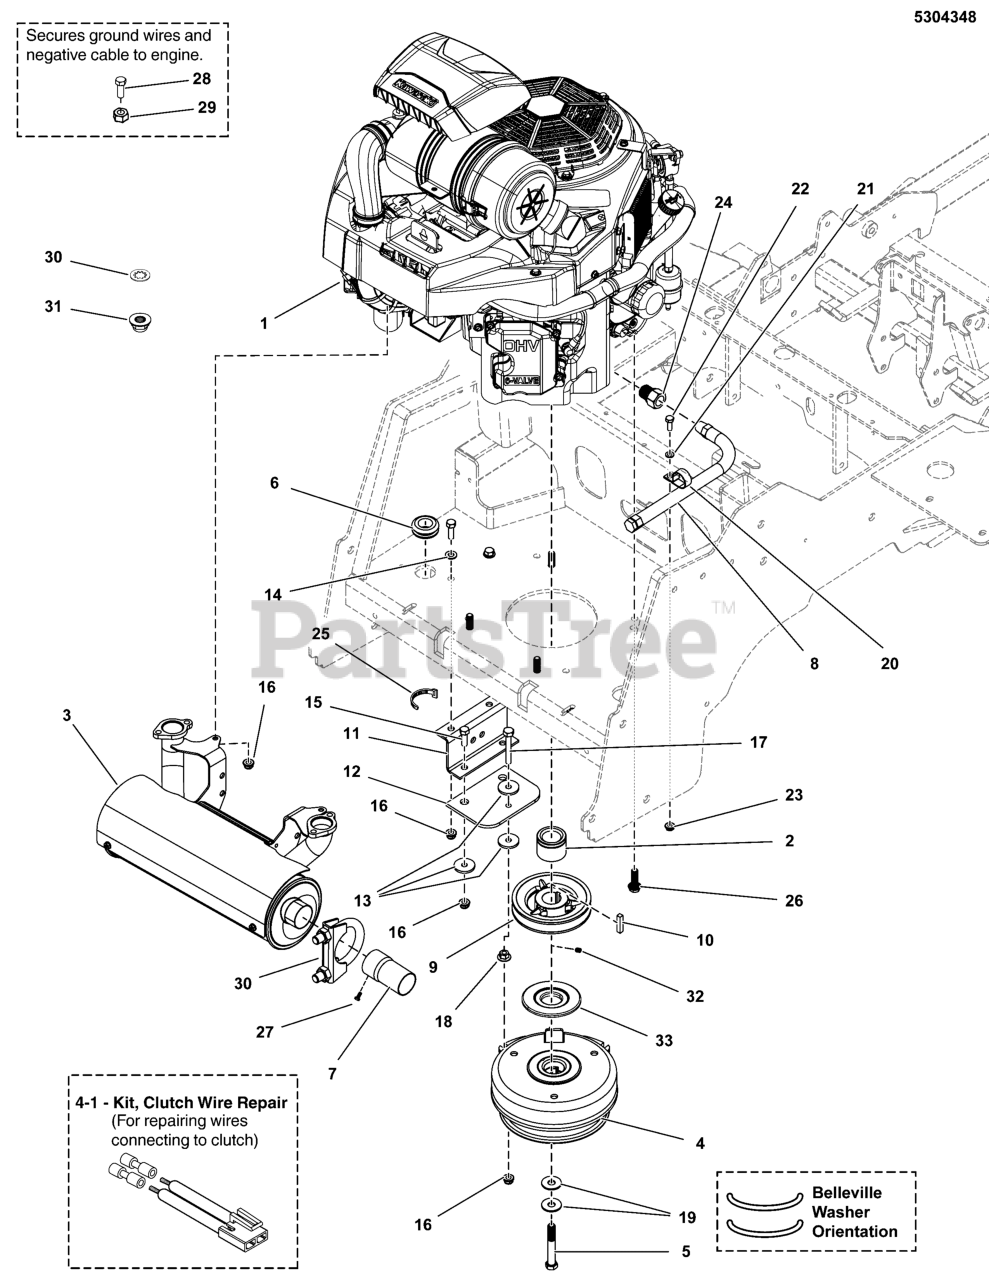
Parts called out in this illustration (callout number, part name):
2	SPACER, 1.13 X 1.75 X 1.35, CZ
3	MUFFLER 35-37HP KAWASAKI 5 CAN
4	CLUTCH, 250 FT-LBS, WATER GUARD
4-1	KIT, CLUTCH WIRE REPAIR
5	BOLT, CRANKSHAFT, 7/16-20 X 3-1/4, GD 8
6	GROMMET, 7/8"ID, 1/4" THICK STK
7	EXTENSION, TAILPIPE, 3" - BLACK
8	HOSE-OIL DRAIN .375ID 16.5L
9	PULLEY, 4.75 OD X 1-1/8 BORE, BC-48
10	KEY, 1/4" SQ. X 1-1/4
11	ANCHOR, CLUTCH, IS600-IS700 - BLK
12	CLUTCH ANCHOR PAD
13	WASHER, .34 X 1.25 X 10 GA
14	WASHER, 5/16" SAE
15	BOLT, 5/16-18 X 1" GRD5 YZ
16	NUT, 5/16-18 HEX NYLOCK FLANGE NUT
17	BOLT, 5/16-18 X 2-1/4 TFL, GD5 YZ
18	NUT, 5/16-18 HEX SERRATED FLANGE (LARGE)
19	BELLEVILLE WASHER, 1.1875 X .442 X .098
20	CLAMP, VINYL INSULATED, 1.00
21	WASHER, 1/4 SAE
22	BOLT, 1/4"-20 X 3/4" GD5 YZ
23	NUT, 1/4-20 HEX SERR. FLANGE
24	ADAPTER, Oil Drain
25	TIE,SELF-LOCKING, 24"
26	BOLT, HEX FLG, SER, GD5 3/8-16 X 1-1/4" PACH CZ
27	SCREW, SELF-TAP, #8-32 X 3/8. WASH HEX, CZ
28	BOLT
29	NUT, HEX, M8-1.25, CZ, GD 8.8
30	WASHER, 5/16" Internal Tooth Lock
31	NUT, M8-1.25 Hex Serrated Flange
32	SET SCREW, 5/16-18 X 3/8, KNURL, W/PATCH
33	WATER GUARD, WARNER C 250 FT-LBS CLUTCH
